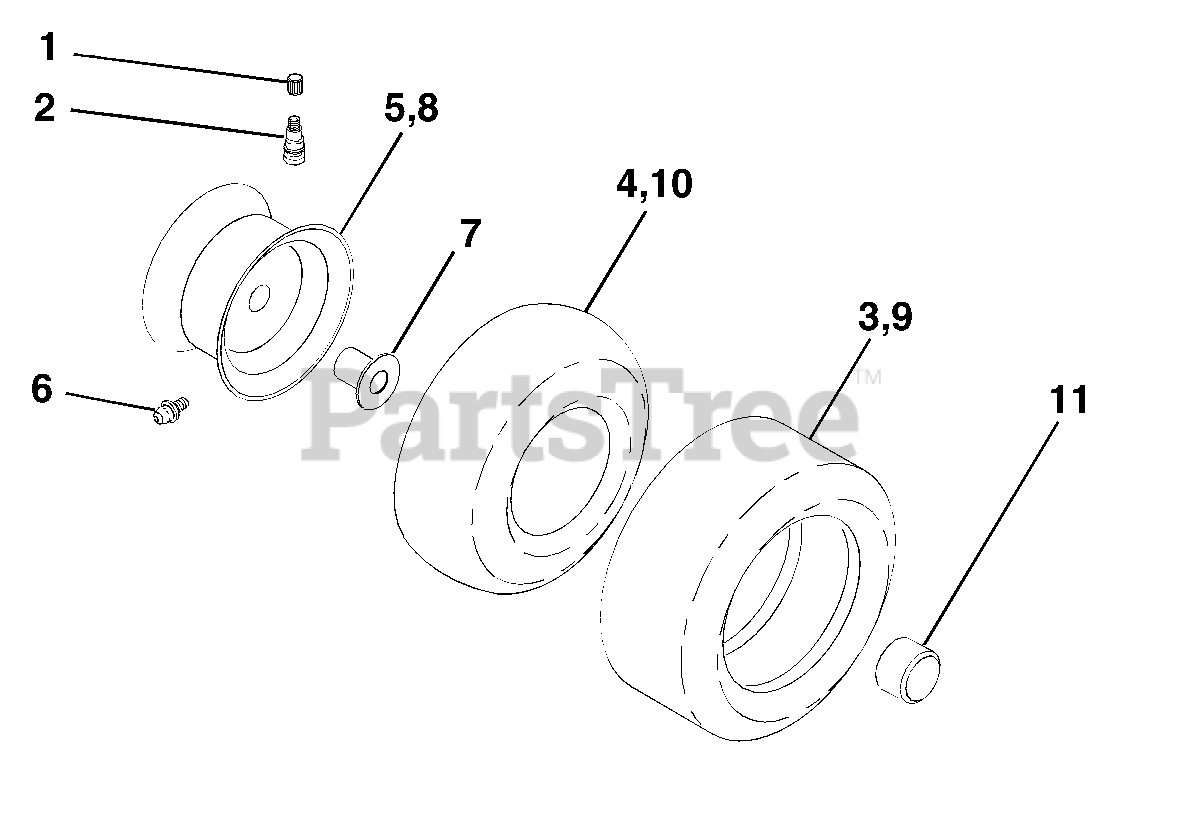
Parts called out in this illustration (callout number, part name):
1	Cap Valve Tire
2	Stem Valve
3	Tire F Ts 15 X 6 0 - 6 Service
4	Tube Front (Service Item Only)
5	Rim Asm 6" front Service
6	Fitting Grease (Front Wheel Only)
7	Bearing Flange (Front Wheel Only)
8	Rim Asm 8" rear Service
9	Tire R Ts 18x9.5-8 C Service
10	Tube Rear (Service Item Only)
11	Cap Axle Blk 1 50 X 1 00
